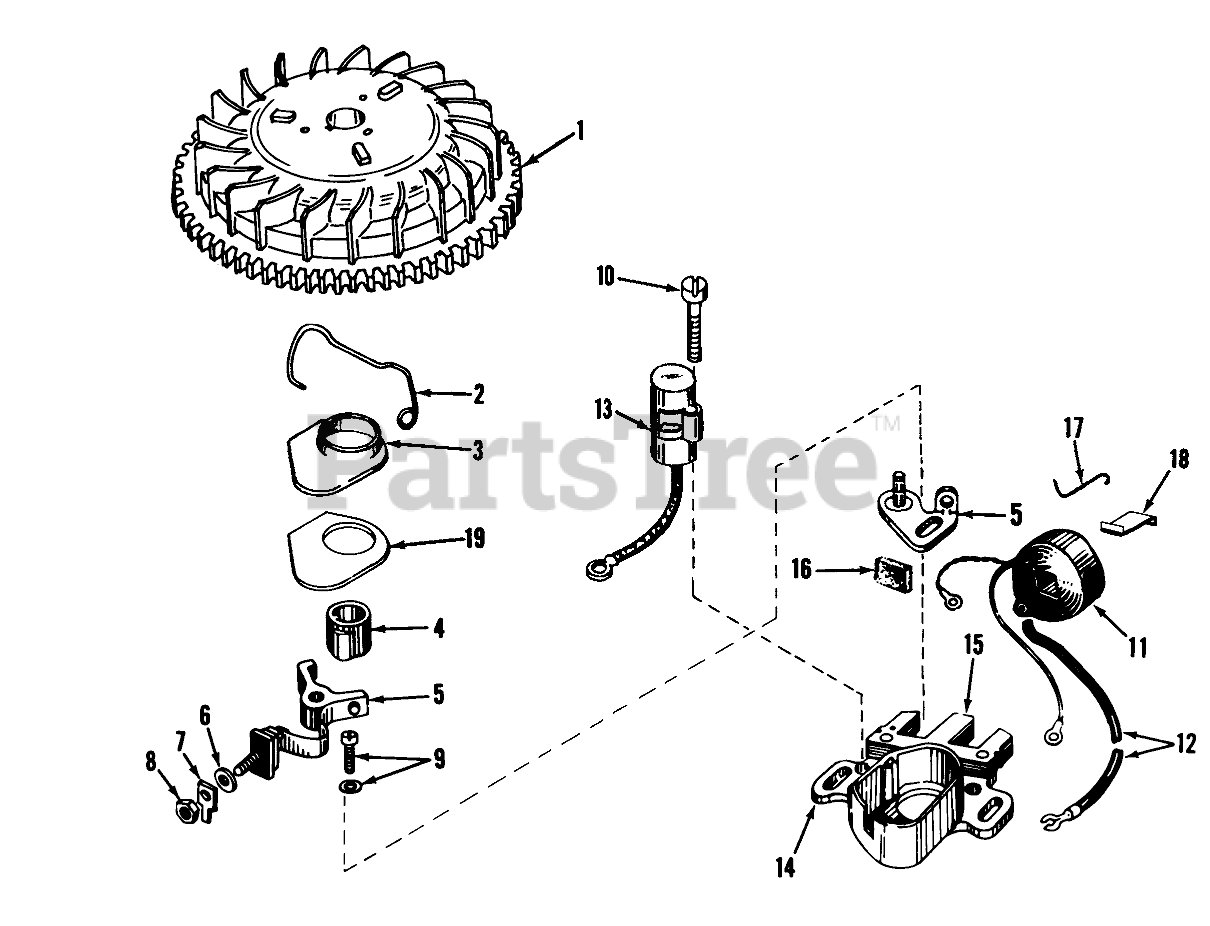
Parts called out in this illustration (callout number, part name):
1	FIywheel
2	Spring Breaker Box
3	Cover, Dust
4	Cam, Breaker
5	Breaker Assy.
7	Terminal
9	Breaker Screw
10	Condenser Screw
11	Coil Assy. (Incl. Ref. Nos. 12, 13 & 18)
12	Wire, Lead
13	Condenser
14	Core & Plate
15	Stator Assy. (Incl. Ref. Nos. 2, 3, 5 thru 14, 16 thru 19)
16	Felt,Cam Wiper
17	Clip, Coil
18	Spring Coil Wedge
19	Gasket Dust Cover
